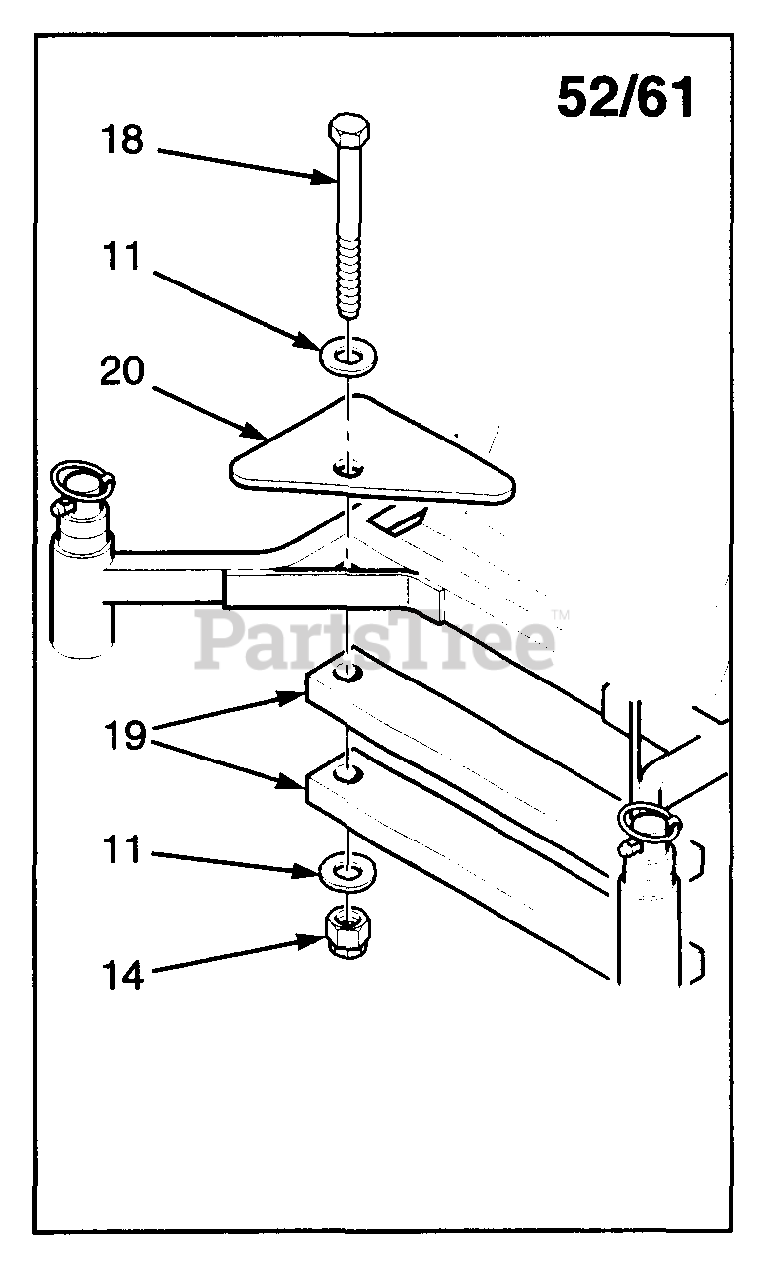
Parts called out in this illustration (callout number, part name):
11	Flat Washer, 3/8 (.391 x .938 x .105)
14	Nut, 3/8-16 Elastic Stop
18	Bolt, 3/8-16 x 6.00" Hex Head
18	Bolt, 3/8-16 x 5.00" Hex Head
19	Weight Bar
20	Mounting Bracket, Weight Bar
